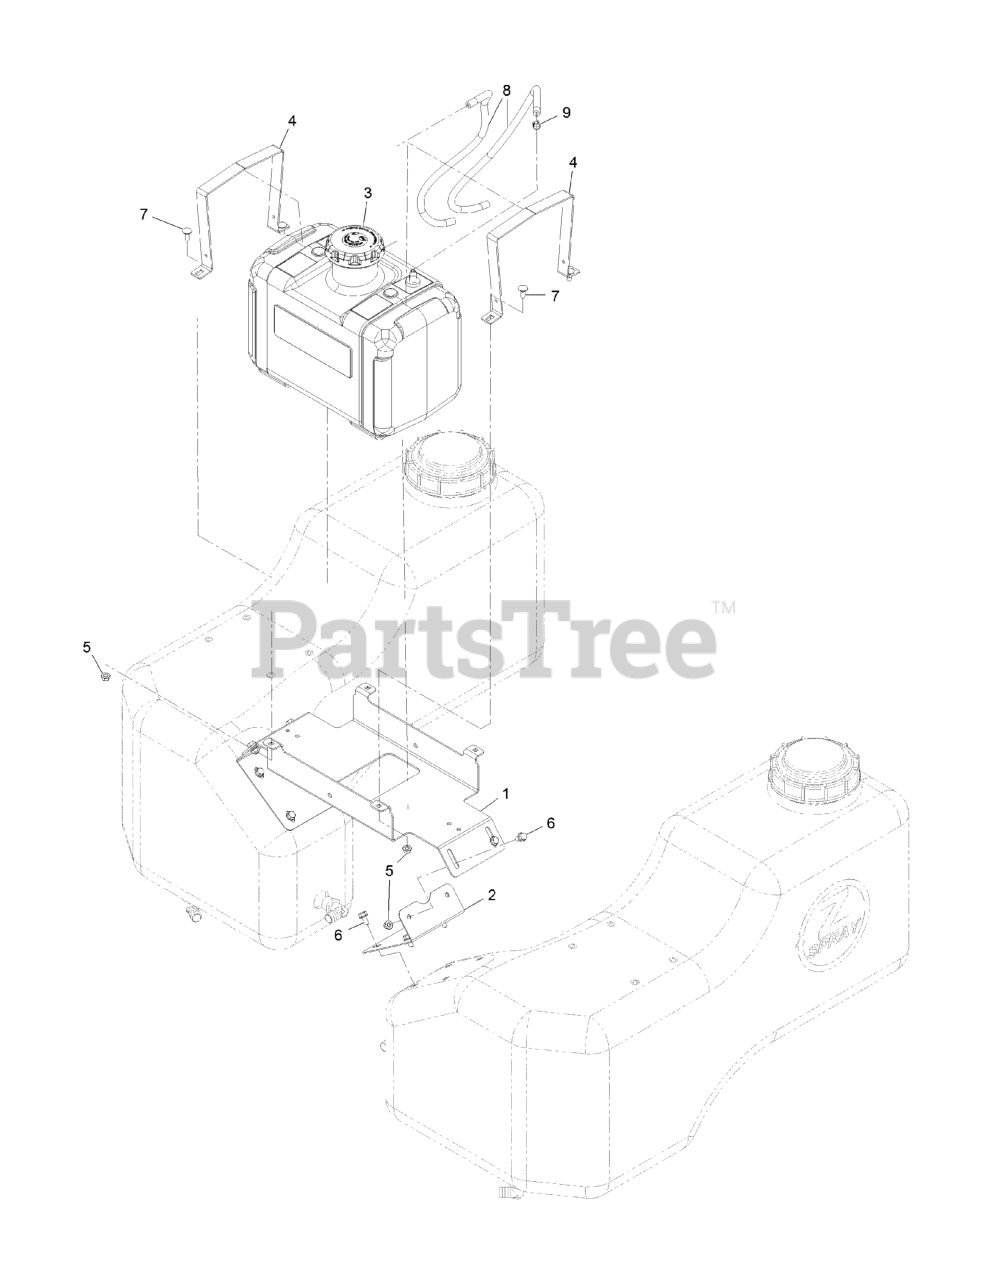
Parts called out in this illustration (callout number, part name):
1	Mount, Gas Tank
2	BRACKET-SUPPORT, GAS TANK
3	ASM-Tank, 5 Gal.
4	Strap, Gas Tank
5	Nut-Hex Flange
6	Screw-HHF
7	SCREW-CARR
8	HOSE-FUEL
9	CLAMP-HOSE
